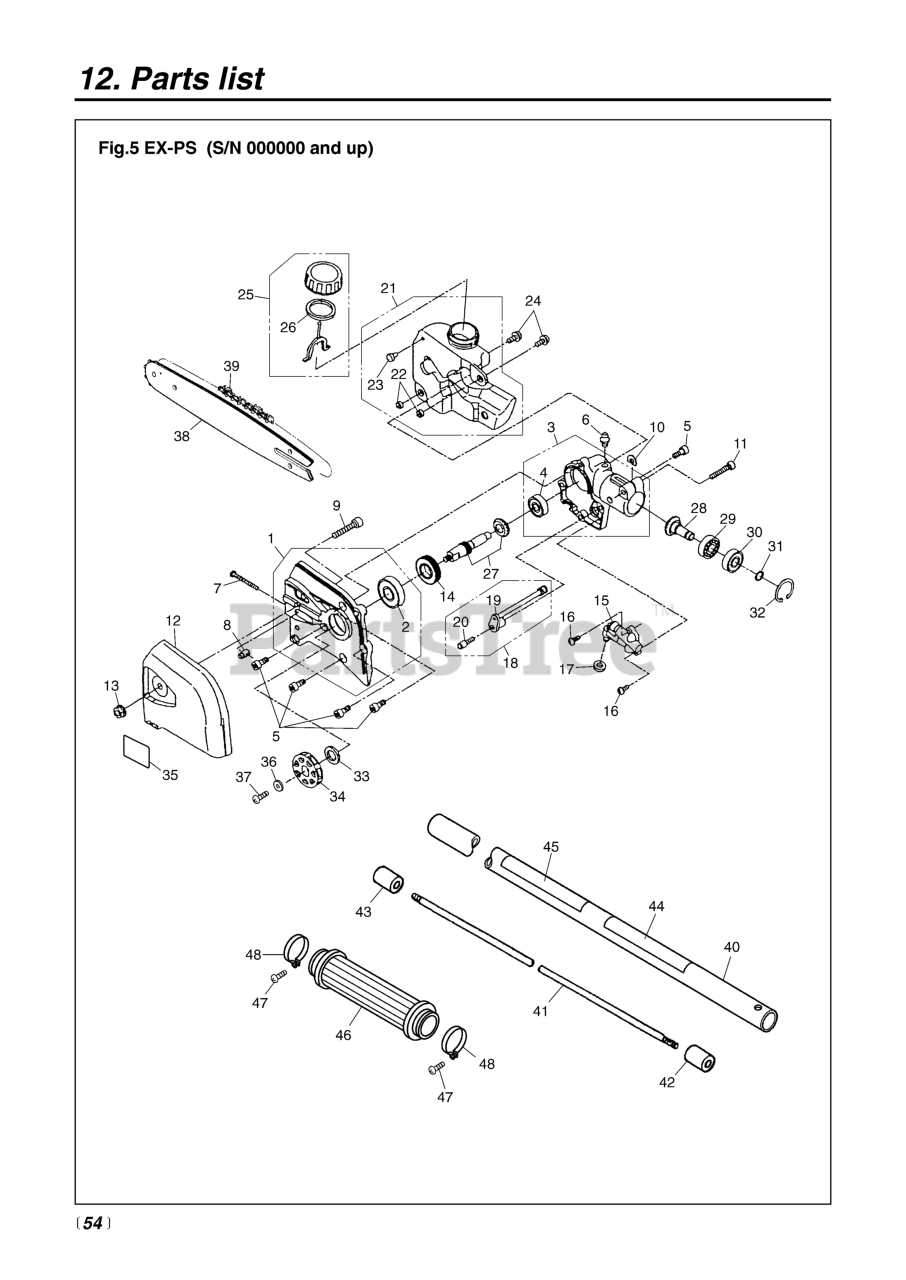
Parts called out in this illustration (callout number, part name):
2	BEARING
3	GEARCASE COMP (RIGHT)
5	BOLT, M5 x 12
6	FITTING, GREASE
7	SCREW
8	NUT
9	BOLT, M6 x 30
10	SHIM
12	COVER, CHAIN
13	NUT
14	GEAR, WORM
15	PUMP ASSY, OIL
16	SCREW, M4 x 10
17	GASKET
18	PIPE ASSY, OIL
19	PIPE, OIL
20	FILTER
21	TANK ASSY, OIL
22	COLLAR
23	VALVE
24	SCREW, M5 X 12
25	CAP ASSY, OIL
26	GASKET, OIL CAP
27	SHAFT, GEAR
28	GEAR, BEVEL
29	BEARING (RPLS T3403-13530)
31	RING, SNAP (RPLS T3300-13330)
32	RING, SNAP, M24 x 1.2
33	COLLAR
34	SPROCKET
35	LABEL (PSZ2500)
36	WASHER
37	SCREW
39	12
40	PIPE COMPLETE
41	SHAFT
42	JOINT, SHAFT (RPLS -12240)
43	SPACER
44	NAMEPLATE
45	PLATE, CAUTION
46	GRIP
48	SCREW (RPLS 00260- )
